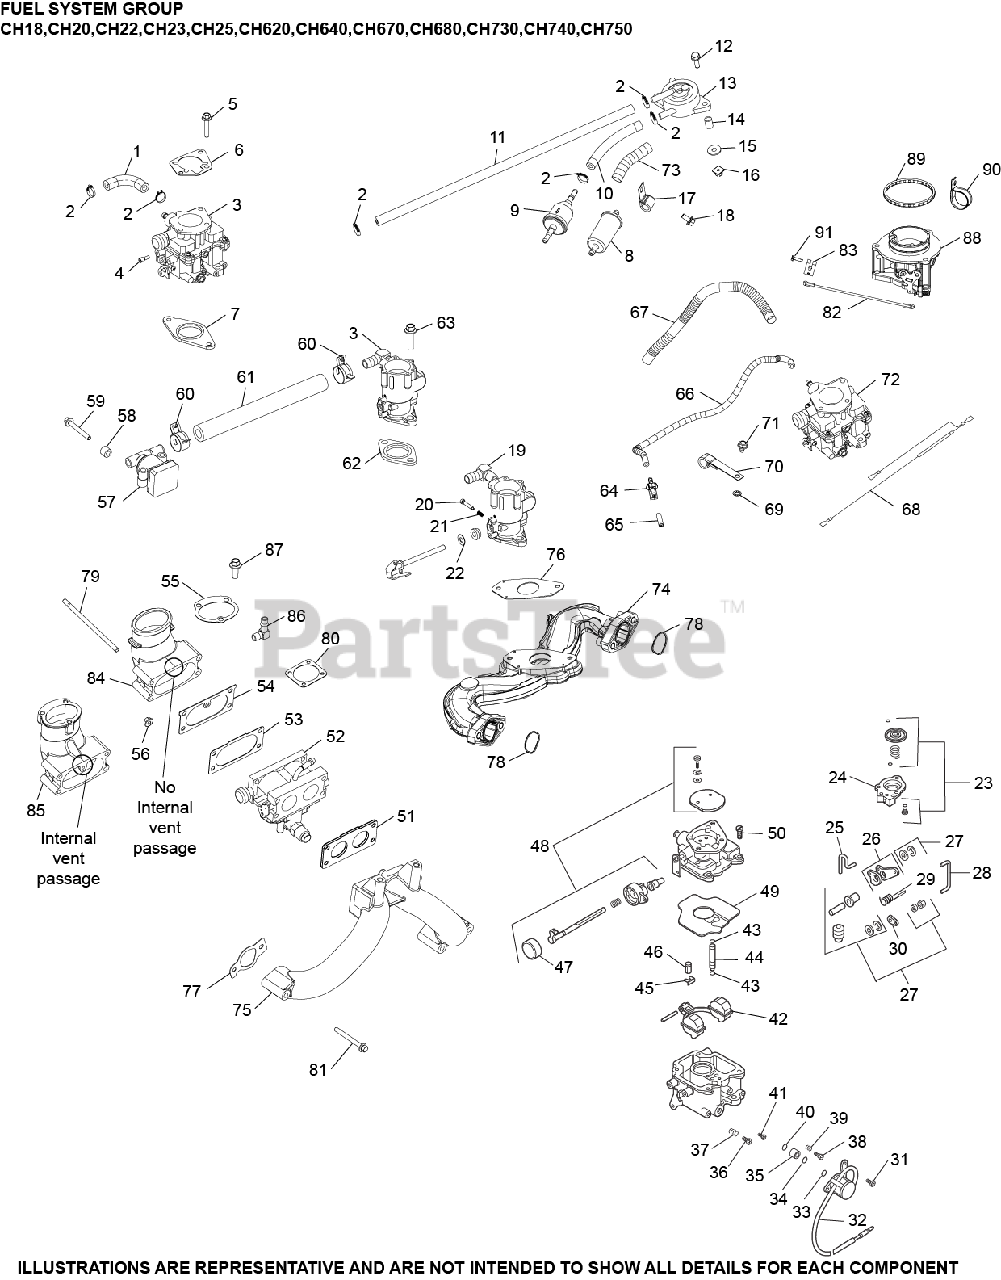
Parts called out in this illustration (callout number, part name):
1	HOSE,LW PERM.FUEL 24.00"-USE 25 111 81-S
2	CLAMP, HOSE (KM)-USE 25 237 31-S
3	KIT, CARBURETOR (TIER III) USE 24 853 258-S
5	SCREW, FLG M6X1.0X25
6	GASKET, AIR CLEANER BASE
7	GASKET, CARBURETOR
8	FILTER, FUEL
64	CONNECTOR, EVAPORATIVE
65	CAP, MASKING
66	HOSE, EVAPORATIVE
68	LEAD, GROUND
69	WASHER, INT TOOTH LOCK 1/4"
73	SLEEVE, ANTI ABRASION -USE 25 431 12-S
74	KIT, INTAKE MANIFOLD
76	GASKET, CARBURETOR
78	O-RING, INTAKE PORT
